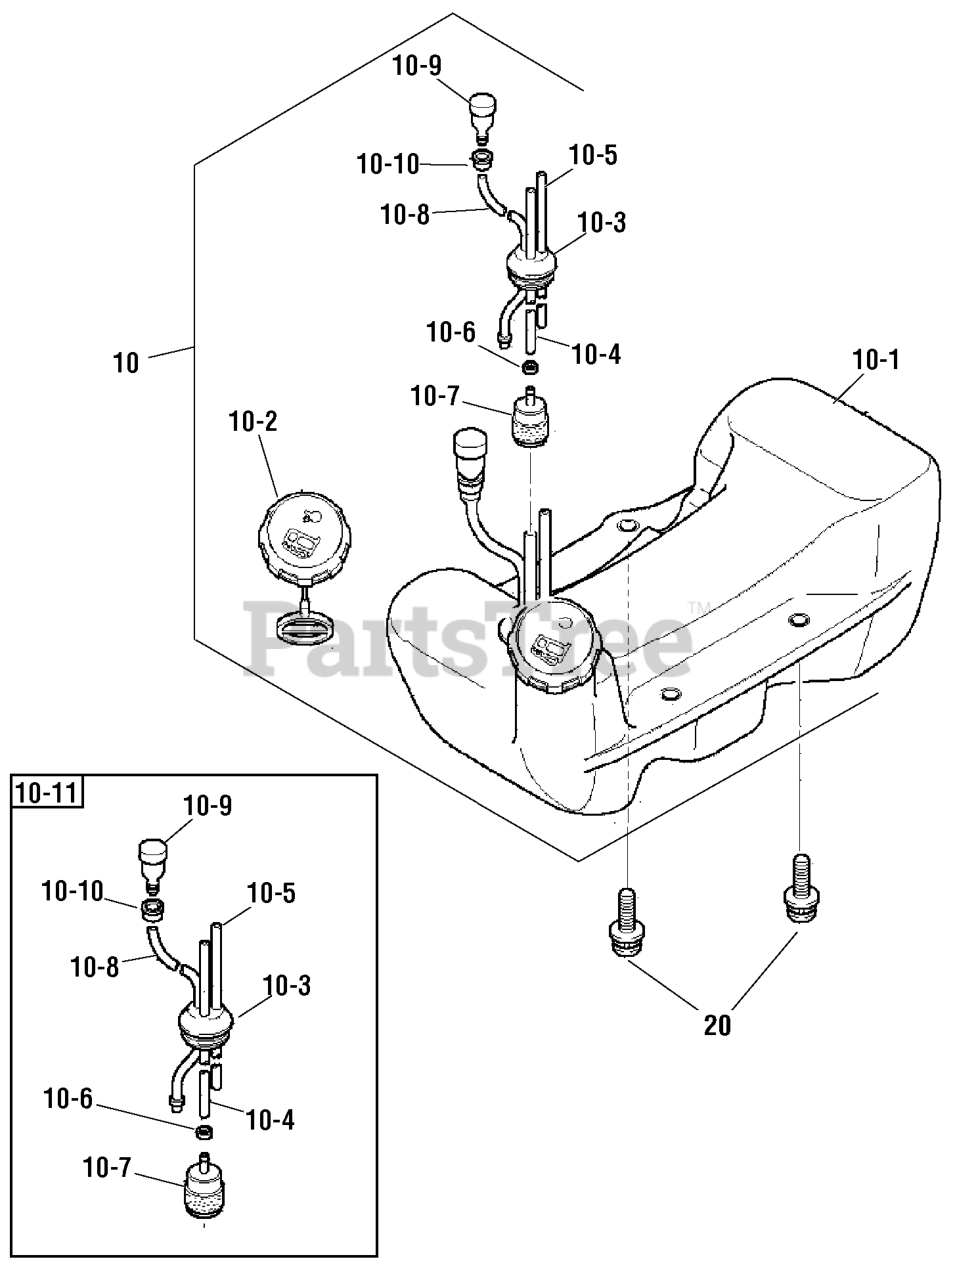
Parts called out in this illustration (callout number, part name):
10	FUEL TANK ASSEMBLY
10-1	FUEL TANK
10-2	FUEL CAP
10-3	GROMMET
10-4	TUBE, Fuel
10-5	TUBE, Fuel
10-6	BUSH
10-7	FILTER, Fuel
10-8	HOSE, Fuel
10-9	VALVE, Breather
10-10	CLIP
10-11	FUEL LINE ASSEMBLY
20	SCREW & WASHER
